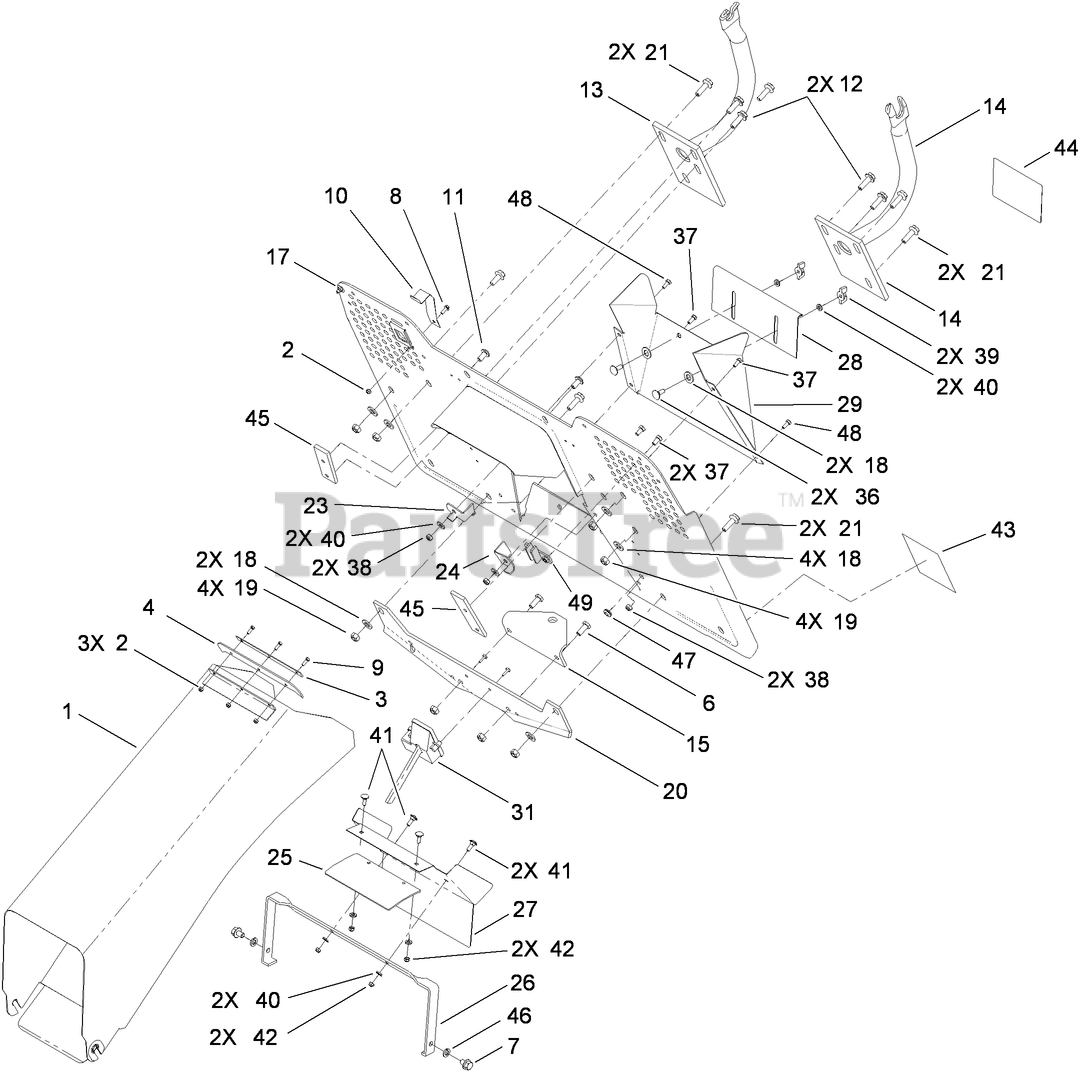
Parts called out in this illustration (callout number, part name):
1	Tunnel
2	NUT-HEX
3	PLATE-SUPPORT
4	SEAL-RUBBER
6	SCREW-HH
7	SCREW-HHF
9	SCREW-SFH
10	BRACKET-BAG PRESENT SWITCH
11	BOLT-CARRIAGE
13	SUPPORT-COLLECTOR, RIGHT
14	SUPPORT-COLLECTOR, LEFT
15	HITCH-TOW
17	COLLECTOR PLATE ASM
18	WASHER-FLAT
19	NUT-LOCK, NI
20	SUPPORT-HITCH, TOW
21	SCREW-HEX
23	Support-Tunnel, Left
24	Support-Tunnel, Right
25	Shield-Rubber
26	BRACKET-SHIELD, PROTECTIVE
27	SHIELD-PROTECTIVE
28	Shield-Adjustable
31	OVERLOAD SWITCH ASM
37	SCREW-HH
38	NUT-LOCK
39	NUT-WING
40	WASHER-FLAT
41	BOLT-CARRIAGE
42	NUT-LOCK
43	DECAL-BYPASS, HYDRO
44	DECAL-POSITION, BAGGING
45	Plate-Reinforcing
48	Screw-HH
49	BRACKET-SUPPORT, FUEL TANK
